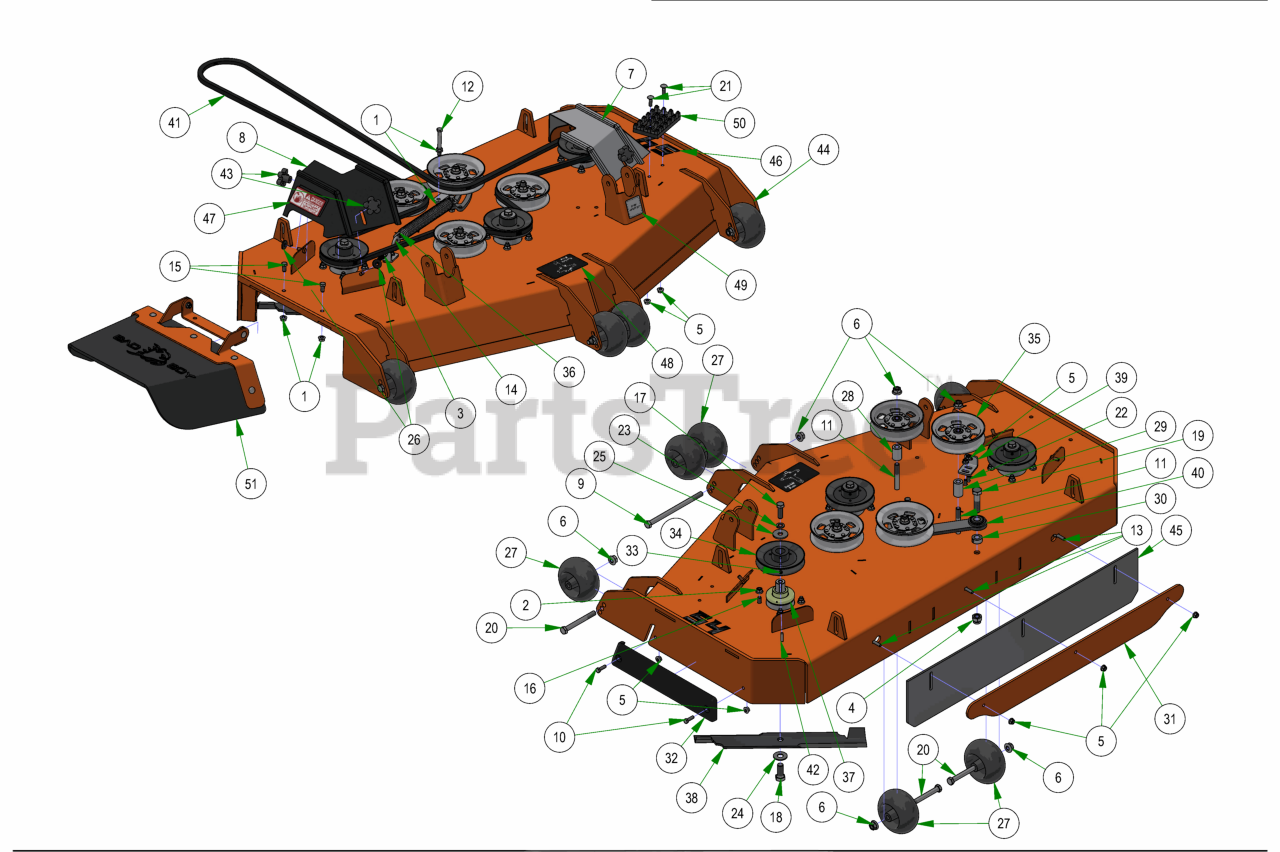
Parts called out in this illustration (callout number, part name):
1	3/8-16 HEX SERRATED FLANGE NUT HARD/ZINC
2	3/8-16 NYLON INSERT FLANGE LOCKNUT (GR.F) ZINC
3	3/8-16 HEX NUT ZINC
4	5/8-11 NYLON INSERT LOCKNUT ZINC
5	5/16-18 NYLON INSERT FLANGE LOCKNUT ZINC
6	1/2-13 NYLON INSERT FLANGE LOCKNUT ZINC
7	2019 54" Left Outlaw Gen2 Pulley Cover
8	2019 54" Right Outlaw Gen2 Pulley Cover
9	1/2-13 X 8 HEX CAP SCREW GR 5 ZINC
10	5/16-18 X 1 HEX CAP SCREW (GR.5) ZINC
11	1/2-13 X 3-1/2 HEX FLANGE BOLT (GR.8) ZINC
12	3/8-16 X 3 HEX CAP SCREW (GR.5) ZINC
13	5/16-18 X 1-1/4 CARRIAGE BOLT ZINC
14	4" 3/8-16 Eye Bolt
15	3/8-16 X 3/4 HEX CAP SCREW (GR.5) ZINC
16	3/8-16 X 1-1/2 HEX CAP SCREW (GR.5) ZINC
17	1/2-20 X 1-1/2 HEX CAP SCREW (GR.5) ZINC
18	5/8-18 X 1-1/2 HEX CAP SCREW (GR.8) ZINC YELLOW
19	5/8-11 X 2-1/2 HEX CAP SCREW (GR.5) ZINC
20	1/2-13 X 4-1/2 HEX CAP SCREW (GR.5) ZINC
21	5/16-18 X 1 CARRIAGE BOLT (GR.8) ZINC
22	5/16-18 X 7/8 CARRIAGE BOLT ZINC
23	1/2 SPLIT LOCKWASHER (GR.8) ZINC/YELLOW
24	5/8 USS FLAT WASHER (1-3/4" OD) GR.8 ZINC YELLOW
25	1/2 BELLEVILLE WASHER (1-5/8 OD X .140 THK) ZINC
26	.360 ID X .983 OD X .120 THICK FLAT WASHER NYLON BLACK
27	2019 Deck Wheel
28	.502 ID X .750 OD X 1.500 Long Spacer
29	1 3/4" Pulley Spacer
30	5/8 SOLID SHAFT COLLAR (W/1 SET SCREW) ZINC
31	61 Bolt in Baffle Deck v2 Stripping Plate
32	REVISED TRIM BUMPER_20180226
33	5/16-24 X 1/4 SOCKET SET SCREW (CUP PT) PLAIN
34	5.25" Deck Spindle Pulley
35	5-3/4 Idler Pulley
36	2019 Outlaw Gen2 Deck Spring
37	OUTLAW SPINDLE ASSEMBLY
38	54" Fusion Blade for Avenger/ZT/Mav/Outlaw/Revolt
39	2019 Deck Eye Bolt Tab
40	2019 Rebel Rogue Deck Idler
41	B165 Belt-60 54" deck Outlaw
42	1/4 X 1 SQ MACHINERY KEY 1018 STL PLN
43	5/16" Knob
44	2019 Sloped 54" Deck
45	R Series Rubber For Deck
46	54" Deck Decal
47	Danger Decal-Spindle/Discharge
48	2019 Rebel & Rogue Deck Belt Route Decal
49	Deck Impact Patent Decal 9591803
50	Deck Step Assembly
51	2019 Outlaw Gen2 Chute Assembly
